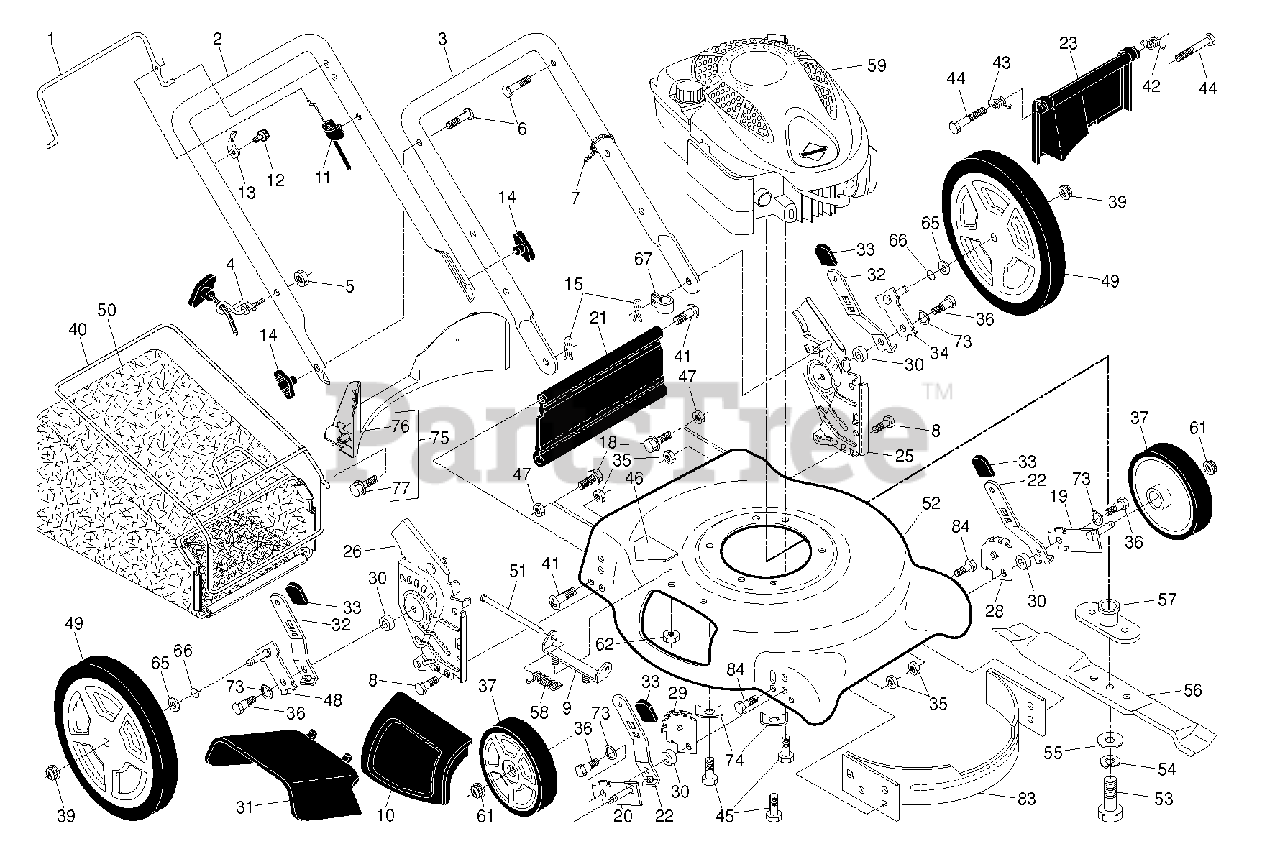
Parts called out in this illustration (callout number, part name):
1	BAIL.CONT.D.STRAIGHT.PUSH.YELL
2	HANDLE.UPPER.ECONOMY.BLACK
3	HANDLE.LOWER.D-STRAIT.BLACK
4	GUIDE.ROPE.STD.BLK.ZIN
5	NUT
6	BOLT, HANDLE 5/16-18X1.75
7	TIE GUIDE
8	BOLT
9	BRACKET.ASM.HOUSING.EZ.MUL
10	MULCH DOOR
11	CABLE.MZR.RATO.22"LOW.
13	BRACKET.UPSTOP.RT
14	KNOB.WING.PLASTIC.BLACK
15	HAIRPIN COTTER
18	SCREW 1/4X20
19	AXLE ARM ASSY FRONT LH
20	AXLE ARM ASSY FRONT RH
21	KIT.SKIRT.21 DOMED.W/LIP
22	SELECTOR SPRING, FRONT
23	REAR DOOR ASSY
25	BRACKET.ASM.HAND.HW.21.LT.BLAC
26	BRACKET.ASM.HAND.HW.21.RT.BLAC
28	BRACKET.ADJ.5.RTAB.LG.HOLE.ABS
29	BRACKET.ADJ.5.LTAB.LG.HOLE.ABS
30	SPACER.HEIGHT.ADJUSTER
31	CLIP ON DISCHARGE GUARD
32	SPRING.SEL.22.ECON.HI-WHL.RATO
33	Knob
34	Axle Arm Assembly, .Lr.5/9.Pos.Bzp
35	NUT.FLANGE.HEX.5/16X18.BLACK
36	SHOULDER BOLT 5/16-18
37	WHEEL.7X1.75.5SPK.BRK.BLACK
39	NUT.HEX.FLANGE.3/8-16.LOCKNUT
40	FRAME.BAG.21.REAR.DOMED.PUSH
41	SCREW.1/4-20X21/4.HEX.
42	SPRING.LH.22.REAR.DOOR.EZ.EMPT
43	SPRING.RH.22.REAR.DOOR.EZ.
45	BOLT 3/8-16X1-1/8
46	No Step Decal
47	NUT.LOCK.5/16-18
48	Axle Arm Assembly, RR 5/9 Pos BZP
49	RP.WHEEL.12X1.75.5SPK.BRK.BLK.
50	GBAG.27510416S.BLK.PPR
51	ROD.HINGE.COMBI-C
52	HOUSING.21".MC.PUSH.YELLOW.E/F
53	SCREW, HEX HD 3/8-24 X 1-3/8
55	WASHER,HARDEN
56	BLADE.21.PUSH/RWGD/FWGD
57	ADAPTER.BLADE.W/KEY.25MM.CE
58	TORSION SPRING
61	NUT.HEX.FLANGE.3/8-16.LOCKNUT
62	LOCKNUT.NYLOC.1/4-20
65	WASHER PM
66	O-RING..070X.487.NEOPRENE
67	CLIP.CABLE.BLK
73	WASHER.CURVED.CYLINDRICAL
74	WASHER.ENGINE.BZP
75	KIT.BAFFLE.REAR.PLASTIC.21.RD
76	BAFFLE.REAR.PLASTIC.21.RD.ECON
77	SCREW.HX.13X.750
83	BAFFLE.FRONT.21.DOME.US
84	BOLT.5/16HEX.WHS.HD
